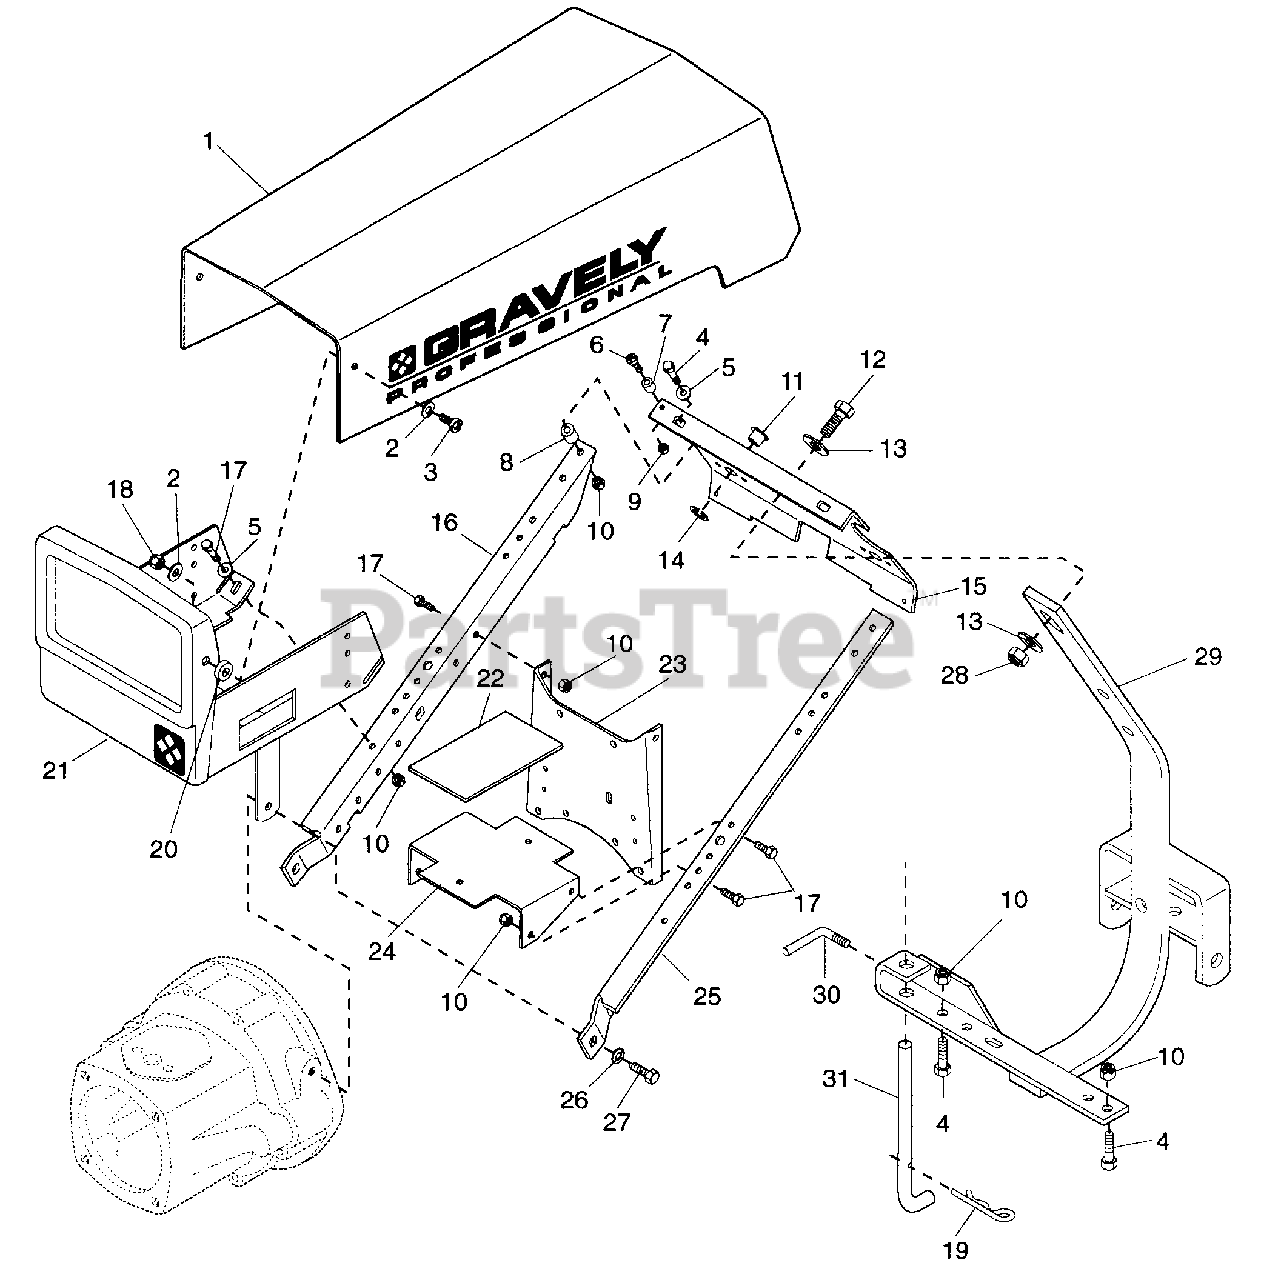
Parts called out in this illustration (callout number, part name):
1	Hood
2	Washer-Flat-Steel .281 x .624 x .065
3	Screw-Machine .250-20 x 1
4	Bolt-Hex .38-16 x 1.50 Grade 5
5	Washer-Flat-Steel .406 x .812 x .065
6	Screw-Machine 6-32 x .625
7	Bumper
8	Bushing
9	Nut-Lock-Machine 6-32
10	Nut-Locking-Nylon .375-16
11	Bushing-Flange .515 x 1.00 x .745
12	Bolt-Hex .625-11 x 2.00
13	Washer-Flat-Steel .656 x 1.250 x .100
14	Ring-Retaining 1.000 x .748
15	Plate, Instrument
16	Support, Handle Bar Right Hand
17	Bolt-Hex .380-16 x .875
18	Nut-Locking-Nylon .250-20
19	Pin-Hair-lnternal .15 x 2.937
20	Bushing-Flange .280 x .750 x .318
21	Weldment, Battery Bracket
22	Pad, Gas Tank
23	Bracket
24	Bracket, Tank Support
25	Support, Handle Bar Left Hand
26	Washer-Lock .50 Reg
27	Bolt-Hex .50-13 x 1 Grade 5
28	Nut-Locking-Nylon .625-11
29	Weldment, Hitch
30	Handle, Adjusting
31	Stand, Kick
